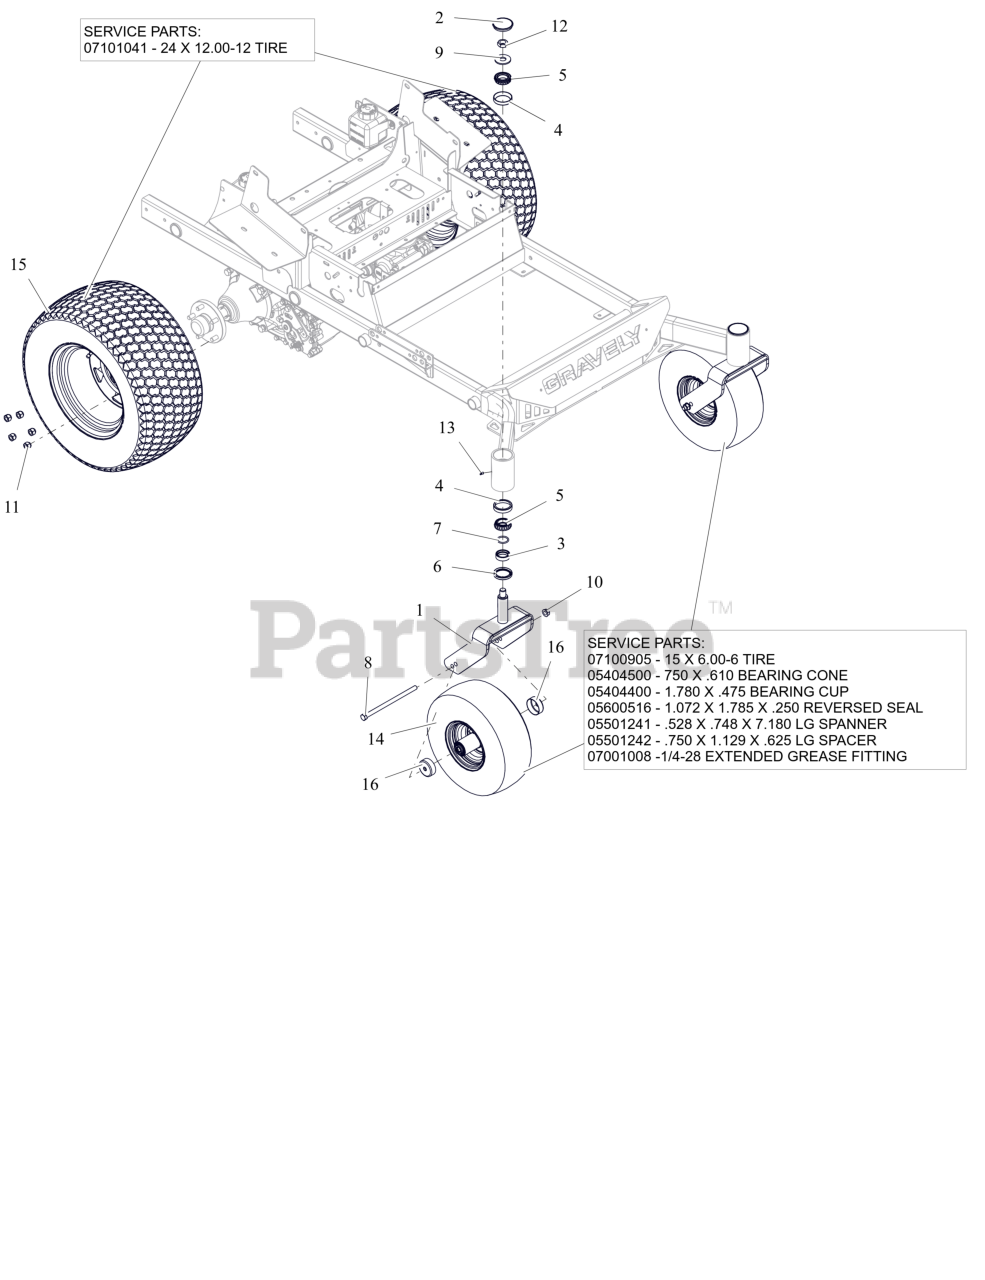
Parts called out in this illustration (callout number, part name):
1	CASTER FORK WMT - RED
2	CAP, DUST
3	SPCR, FRONT CASTER FORK
4	BRG-CUP 2.328X.465
5	BRG-CONE 1.25X.66
6	SEAL, OIL 1.75 X 2.332 X .312
8	BLT, HEX .50-13X9.00 G5 ZCC
9	WSHR-FL-STL 0.812X2X0.148 ZCC
10	NUT-LK-CTR-FLG .500-13 GG ZCC
11	NUT, WHEEL .50-20 ZCC
12	NUT, JAM-TOPLOCK .750-16 ZCC
13	FTG, .25-28 FLUSH MNT GREASE
14	ASM, WHL/TIRE 15X6.00-6 SMOOTH
14	TIRE, 15X6-6 SMOOTH
14	BRG-CONE .750X.61
14	BRG-CUP 1.781X.475
14	SEAL,1.072X1.785X.250 REVERSED
14	SPANNER, .528X.748X7.18 LG
14	SPACER, .750X1.129X.625 LG
14	GREASE FITTING 1/4-28 EXTENDED
14	TUBE 15X6-6
15	ASM, WHL/TIRE 24X12.00-12 K500
15	TIRE, 24 X 12.00-12
16	SHIELD, WHEEL BEARING
